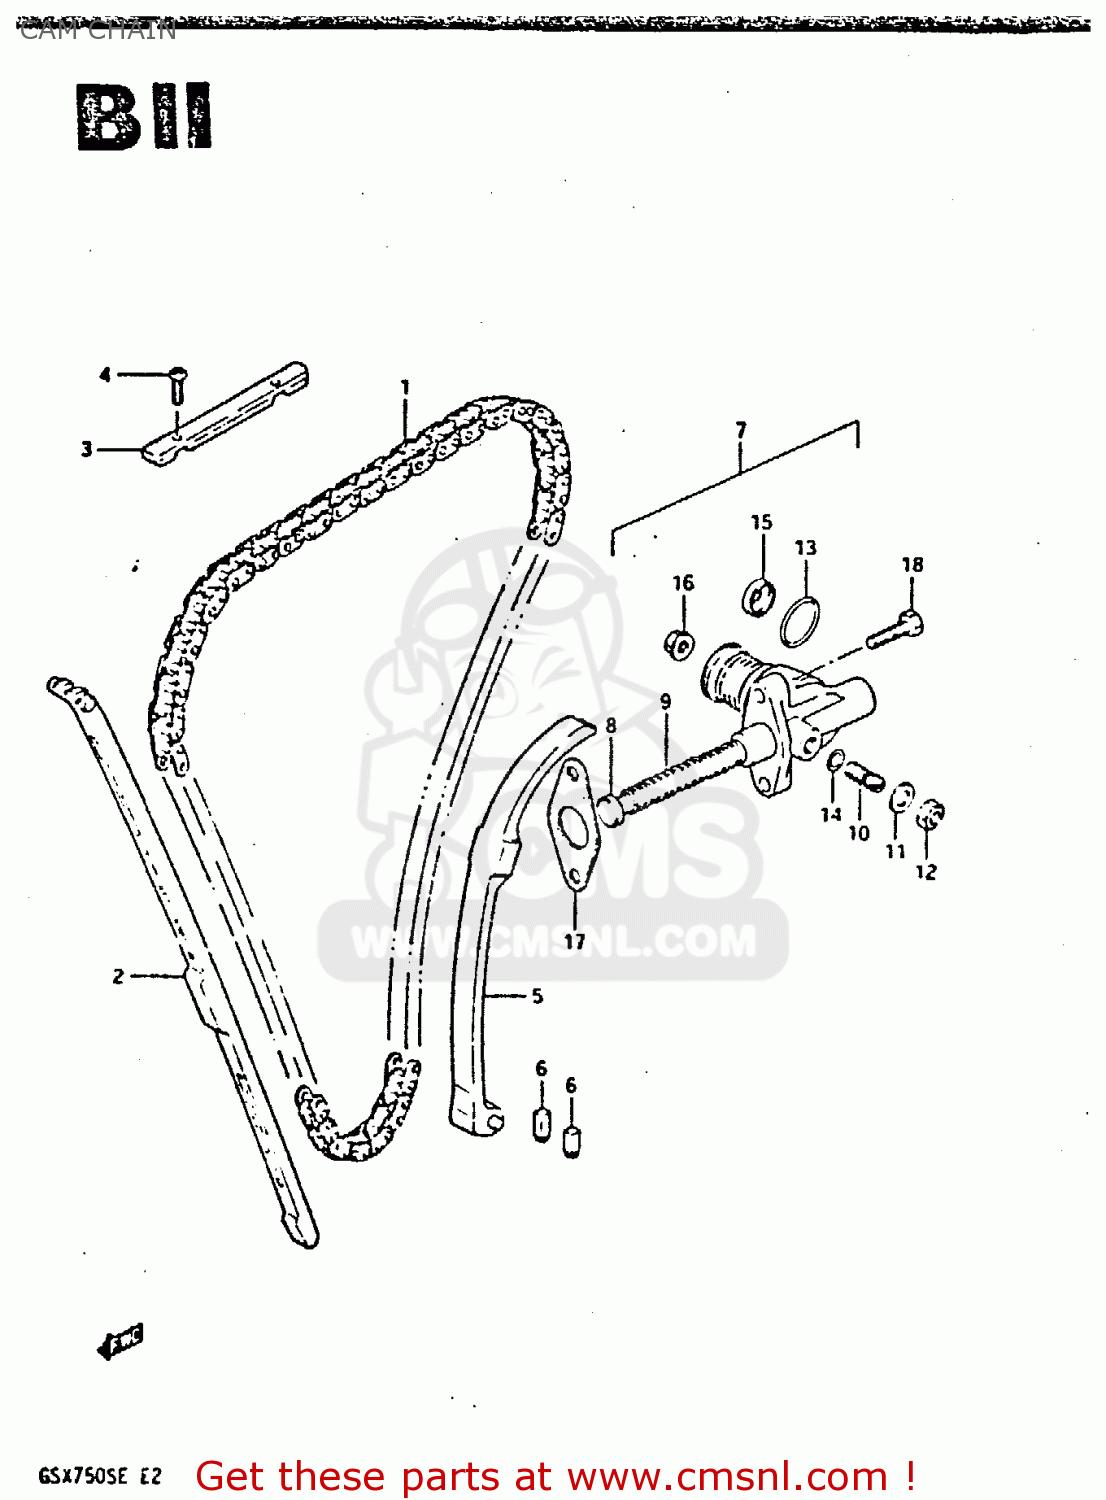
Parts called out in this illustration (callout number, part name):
1	CHAIN,CAMSHAFT DRIVE(120L)
2	GUIDE,CAM CHAIN NO.1
3	GUIDE,CAM CHAIN NO.3
4	SCREW
5	TENSIONER
6	CUSHION,CAM CHAIN TENSIONER
7	ADJUSTER ASSY,TENSIONER
8	ROD,PUSH
9	SPRING
10	SCREW,TENSIONER ADJUST
11	WASHER
12	NUT
13	O RING(D:2.4,ID:20.8)
14	O RING(D:1.9,ID:5.7)
15	SEAL,OIL(10X16X4)
16	NUT 6MM
17	GASKET,TENSIONER ADJUSTER (MCA)
18	SCREW
